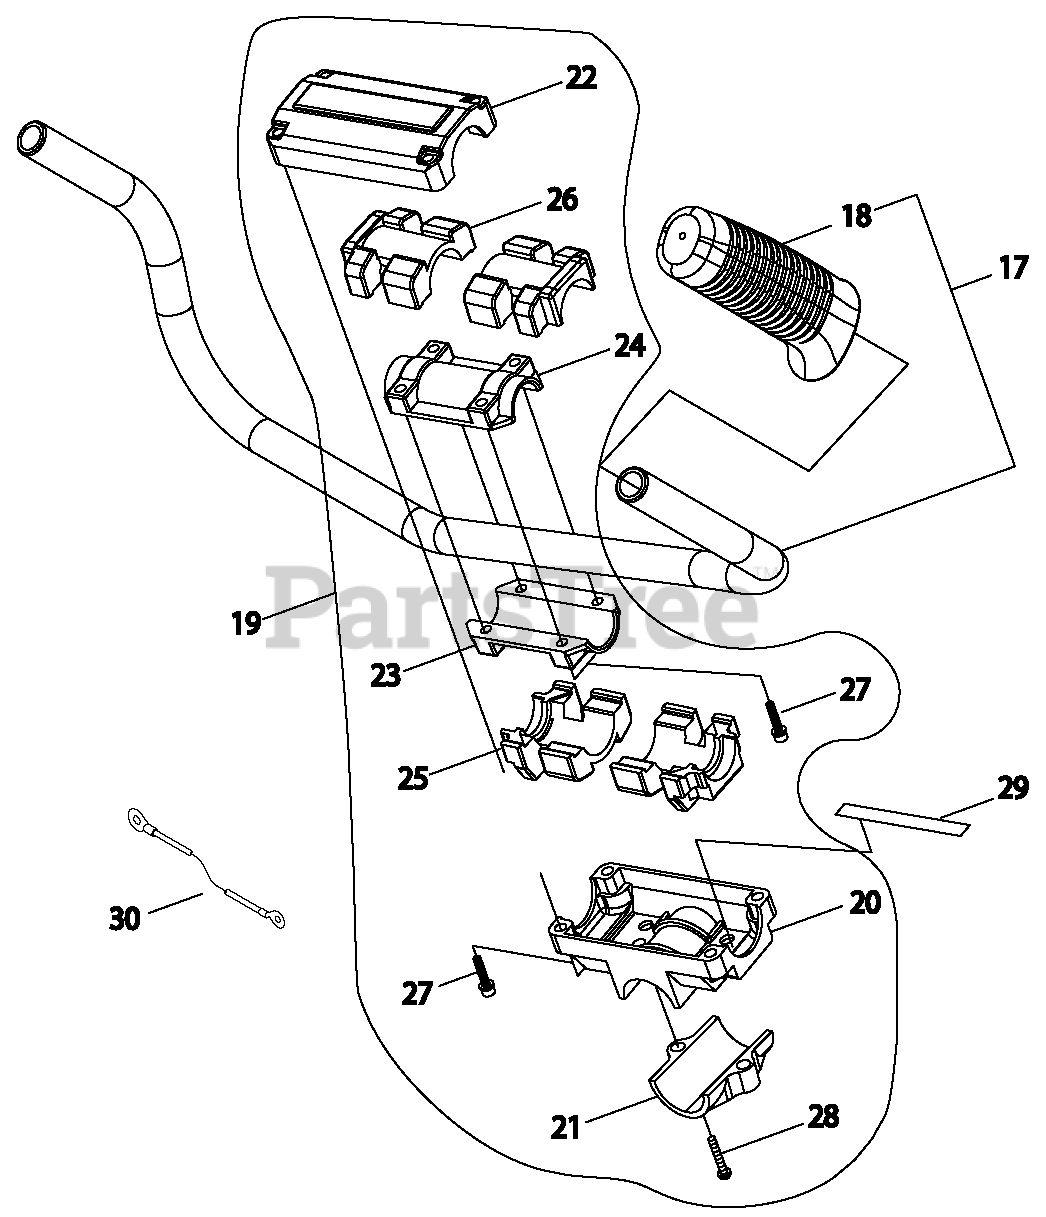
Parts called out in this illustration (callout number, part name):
17	HANDLE ASSY
18	GRIP
19	BRACKET KIT - HANDLE
20	BRACKET, HANDLE - LOWER
21	BRACKET, MOUNTING
22	BRACKET, HANDLE - UPPER
23	CLAMP - LOWER
24	CLAMP - UPPER
25	CUSHION - LOWER
26	CUSHION - UPPER
27	SCREW - 5X25
28	SCREW - 6X25
29	LEAD - GROUND
30	LEAD - GROUND
